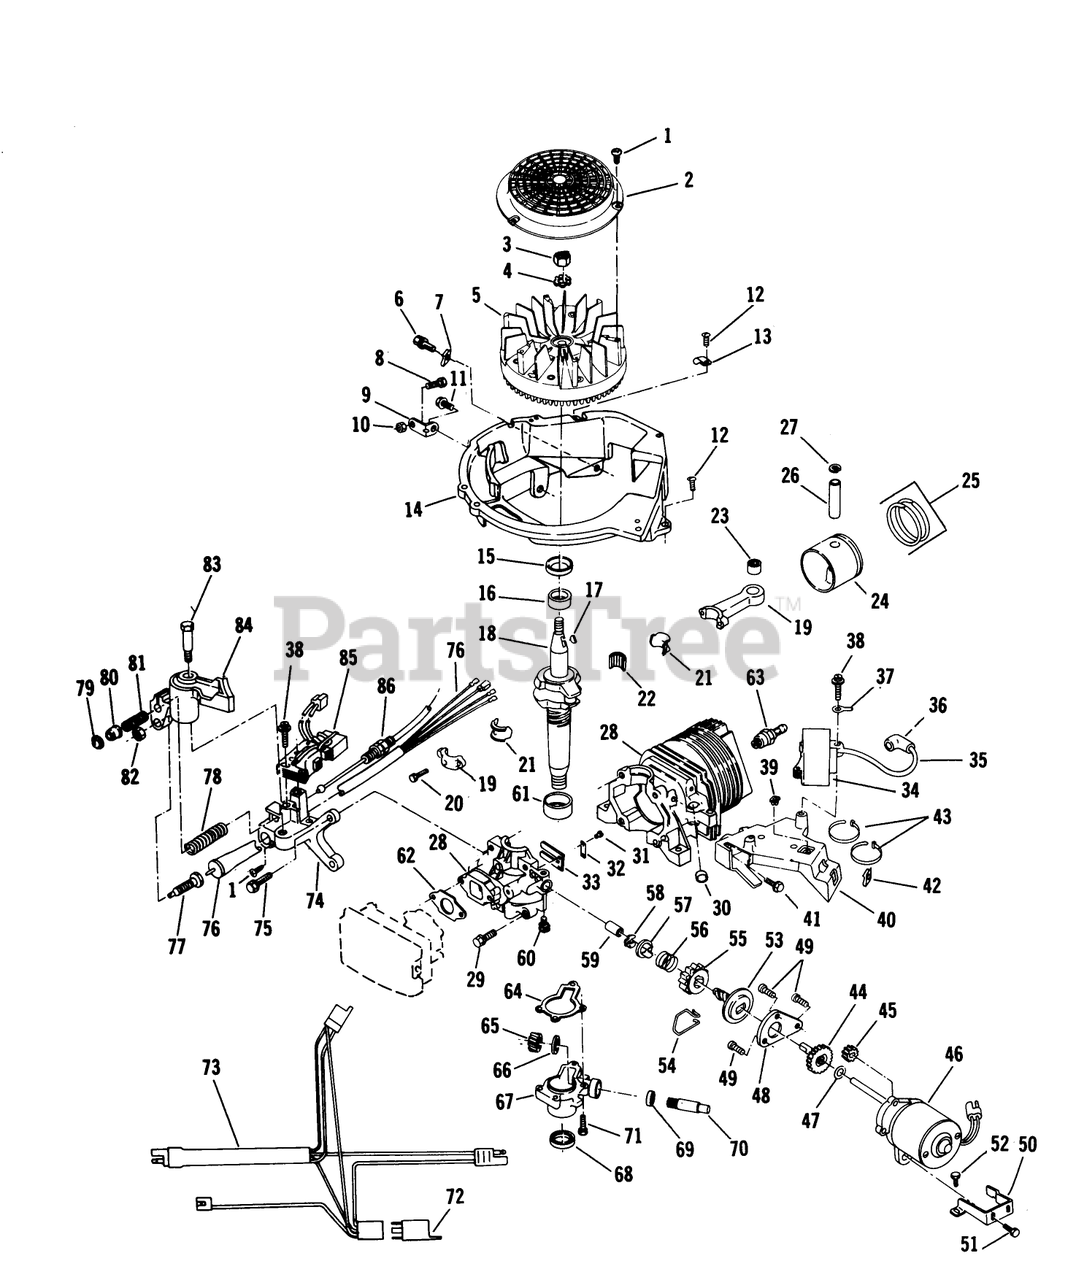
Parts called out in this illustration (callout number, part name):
1	SCREW F
2	SCREEN F'WHEEL S
3	NUT
6	SCREW-SEMS
8	BOLT F
10	NUT-LOCK F
12	SCREW F
14	BASE SHROUD F
16	BEARING V
17	KEY
20	SCREW-HSH
21	LINER ASM
23	BEARING AY F
27	RING-RETAINING
29	SCREW S
30	PLUG-CORE VF
32	PLATE-BACKUP, REED
35	HT LEAD&COVER XEV
37	TERMINAL S
39	NUT-CLIP
42	NUT - SPEED S
44	GEAR-DRIVEN
45	*PINION EF
49	SCREW EF
50	BRACKET
51	SCREW
54	SPRING F
55	PINION EF
56	*SPRING PINION EF
58	RET.RING EF
59	SLEEVE F
61	BEARING S
62	GASKET CARB S
64	GASKET S
65	GEAR, DR SHAFT S
66	THRUST WASHER
68	SEAL-OIL
69	SEAL S
74	BRACKET F
77	PLUNGER S
78	SPRING-BRAKE
79	RETAINER S
80	ACTUATOR-LEVER, BRAKE
81	SPRING
86	CONTROL CABLE
